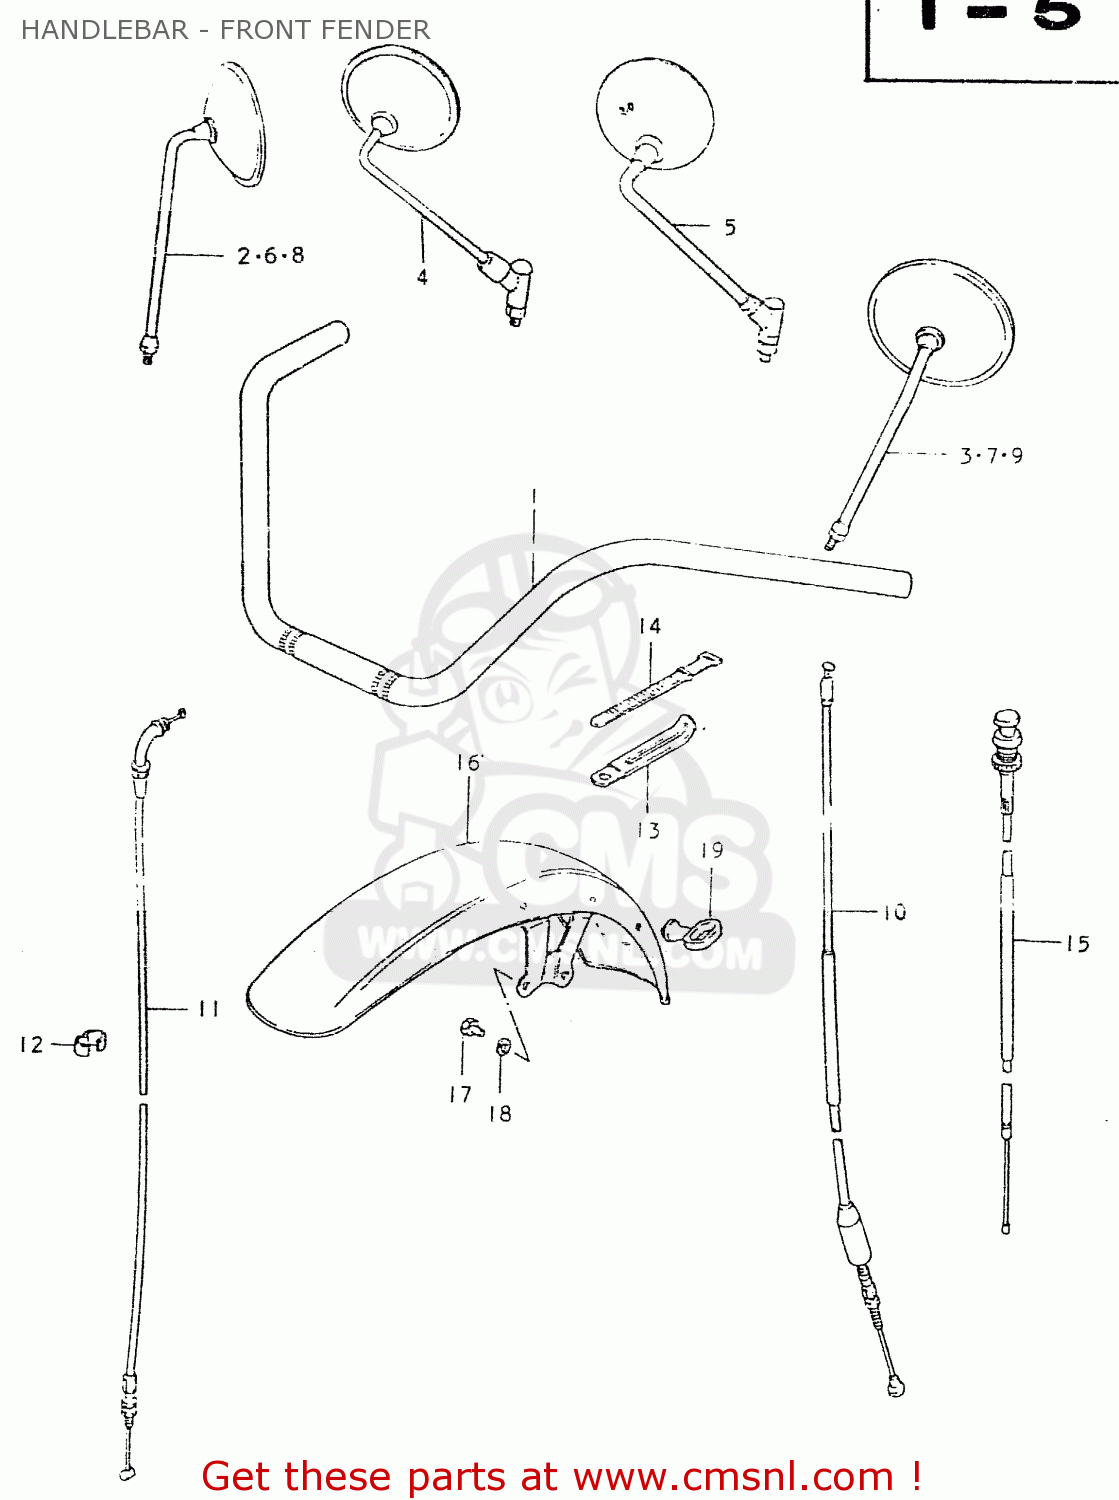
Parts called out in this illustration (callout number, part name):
1	HANDLEBAR
2	MIRROR ASSEMBLY,REAR VIEW
3	MIRROR ASSEMBLY,LEFT
4	MIRROR ASSY,RH
5	MIRROR ASSY, REAR VIEW
6	MIRROR, REAR VIEW RH
7	MIRROR, REAR VIEW LH
8	MIRROR, REAR VIEW RH
9	MIRROR, REAR VIEW LH
10	CABLE ASSY,CLUTCH
11	CABLE ASSEMBLY,THROTTLE
12	CLIP
13	CLAMP
14	CLAMP
15	CABLE ASSEMBLY,STARTER
16	FENDER,FRONT
17	BOLT
18	LOCK WASHER
19	GUIDE,CABLE
